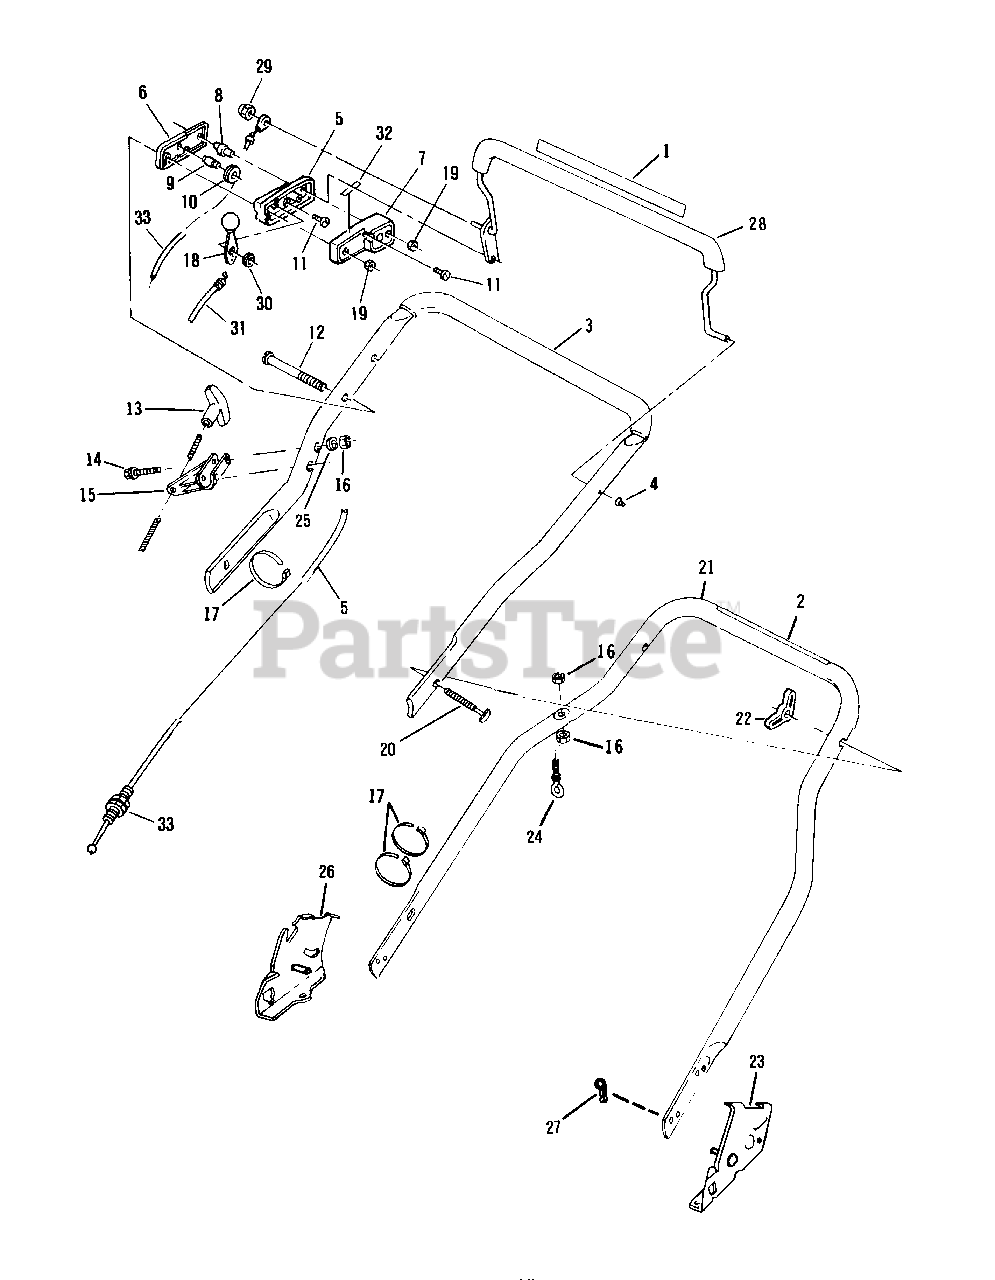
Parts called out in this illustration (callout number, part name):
1	Decal-Engine/Blade Control
2	Decal-Starting Instructions
3	Top Handle
4	Pushnut
5	Control Case-Center
6	Control Case-Outer
7	Control Case-Inner
8	Column
9	Pin
10	Pulley
11	Screw
12	Screw
13	Handle Starter
14	Screw-Truss Head
15	Rope Guide Assembly
16	Locknut
17	Tie Strap
18	Lever and Knob Assembly
19	Nut-Hex-Centerlock
20	Screw
21	Handle-Bottom
22	Knob
23	Bracket-Handle-L.H.
24	Eyebolt
25	Washer
26	Bracket-Handle-R.H.
27	Hair Pin-Handle Bracket
28	Control Lever and Nut Assembly
29	Nut-Acorn
30	Washer-Spring
31	Cable-Throttle
32	Decal-Throttle
33	Control Cable Assembly
